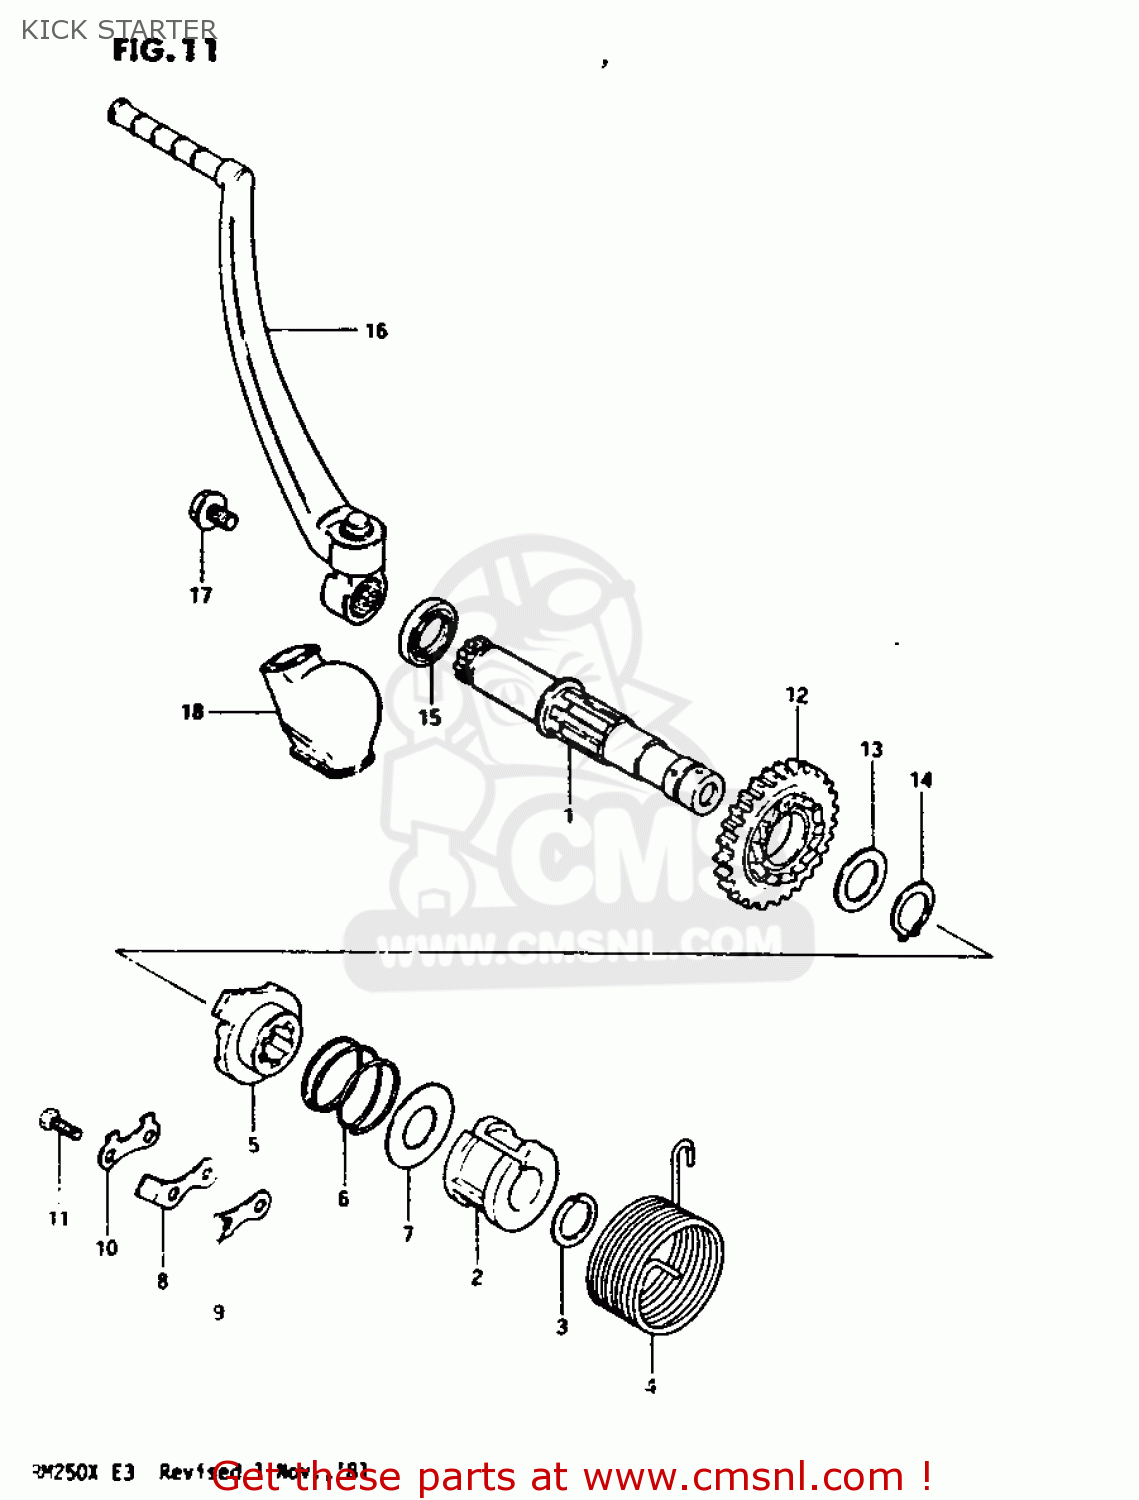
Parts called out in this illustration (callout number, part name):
1	SHAFT,KICK STARTER
2	GUIDE,KICK STARTER SFT SPRING
3	CIRCLIP
4	SPRING
5	STARTER,KICK
6	SPRING
7	WASHER
8	GUIDE,KICK STARTER
9	STOPPER,KICK STARTER
10	WASHER
11	BOLT
12	GEAR
13	SHIM
14	CIRCLIP
15	SEAL,OIL(20X27X5)
16	LEVER ASSY,KICK STARTER
17	BOLT(8X14)
18	COVER,KICK STARTER LEVER JOINT
